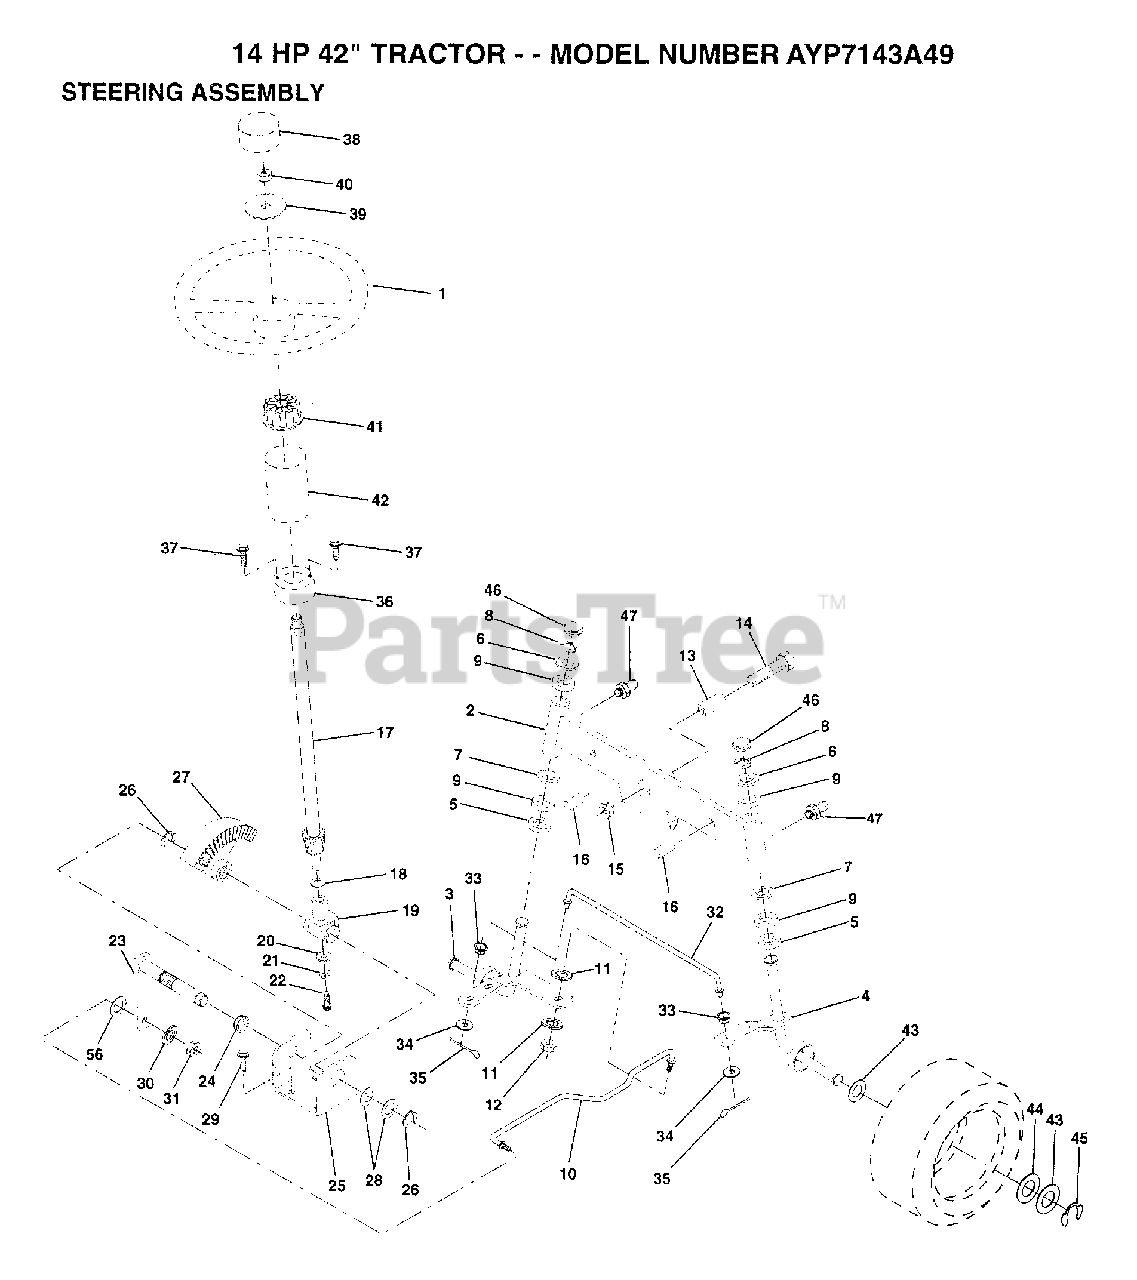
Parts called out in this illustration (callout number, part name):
3	SPINDLE LH
4	SPINDLE RH
5	WASHER .T
6	WASHER
7	WASHER
8	RING
9	COL. SRTG. BEAR.
11	LOCKWASHER
13	BEARING
14	BOLT HEX 5/8-11
15	"NUT-LOC,FLANGE LT"
16	AXLE PIN
17	SHAFT ASM
18	THRUST WASHER
19	SUPPORT.SHAFT
21	LOCKWASHER
22	"SCREW,SPECIAL"
24	NYLINER T
25	"BRKT,STEERING"
26	RING
27	GEAR SECTOR
28	WASHER .T
29	SCREW
30	LOCKWASHER
32	TIE ROD
33	BUSHING.DRAGLINK
34	WASHER
35	COTTER PIN
38	ST WHL INSERT CAP
39	WASHER T
40	GRIPCO NUT
41	ADAPTER-WHEEL LT
42	"TUBE, STR SHAFT"
43	WASHER
44	WASHER
45	RING
46	CAP
47	ZERK M
56	WASHER
